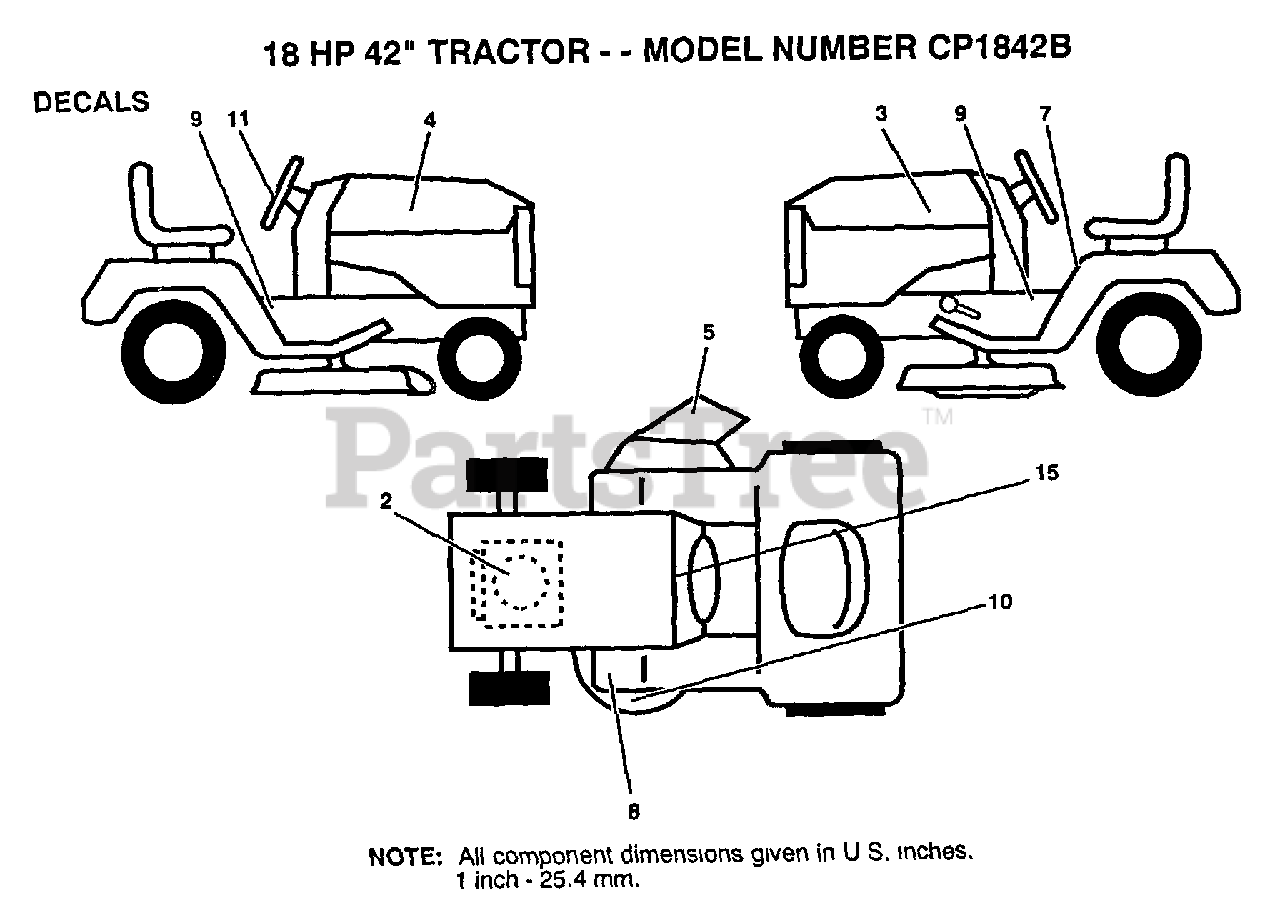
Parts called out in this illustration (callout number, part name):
2	DECAL.ENG.272757
4	DECAL HOOD STRIPE RH
5	DECAL WARING
7	DECAL
9	CHASSIS DECAL
10	DECAL INSTRUCTION CAUTION
11	"DECAL,STRG WHL"
